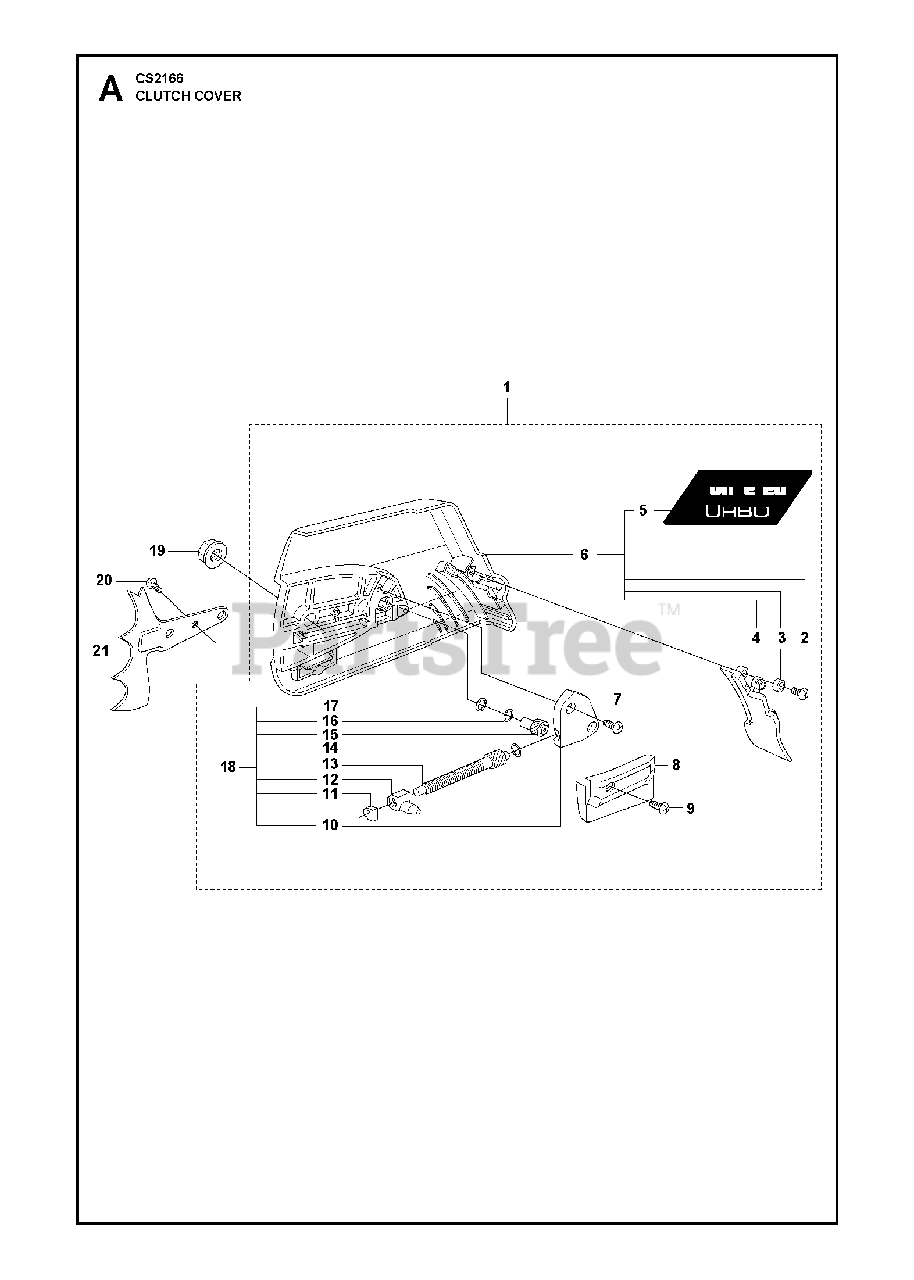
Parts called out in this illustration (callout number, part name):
1	CLUTCH COVER
2	SCREW
3	WASHER
4	PROTECTOR
5	DECAL
6	CLUTCH COVER
7	SCREW
8	GUIDE
9	SCREW
10	COVER
11	SLEEVE
12	COUPLING
13	WORM SCREW / ADJUSTER
14	WASHER
15	RP ADJUSTER
16	WASHER
17	O-RING
18	KIT-CHAIN TENSIONER
19	NUT M8 FLANGE
21	FELLING DOG
